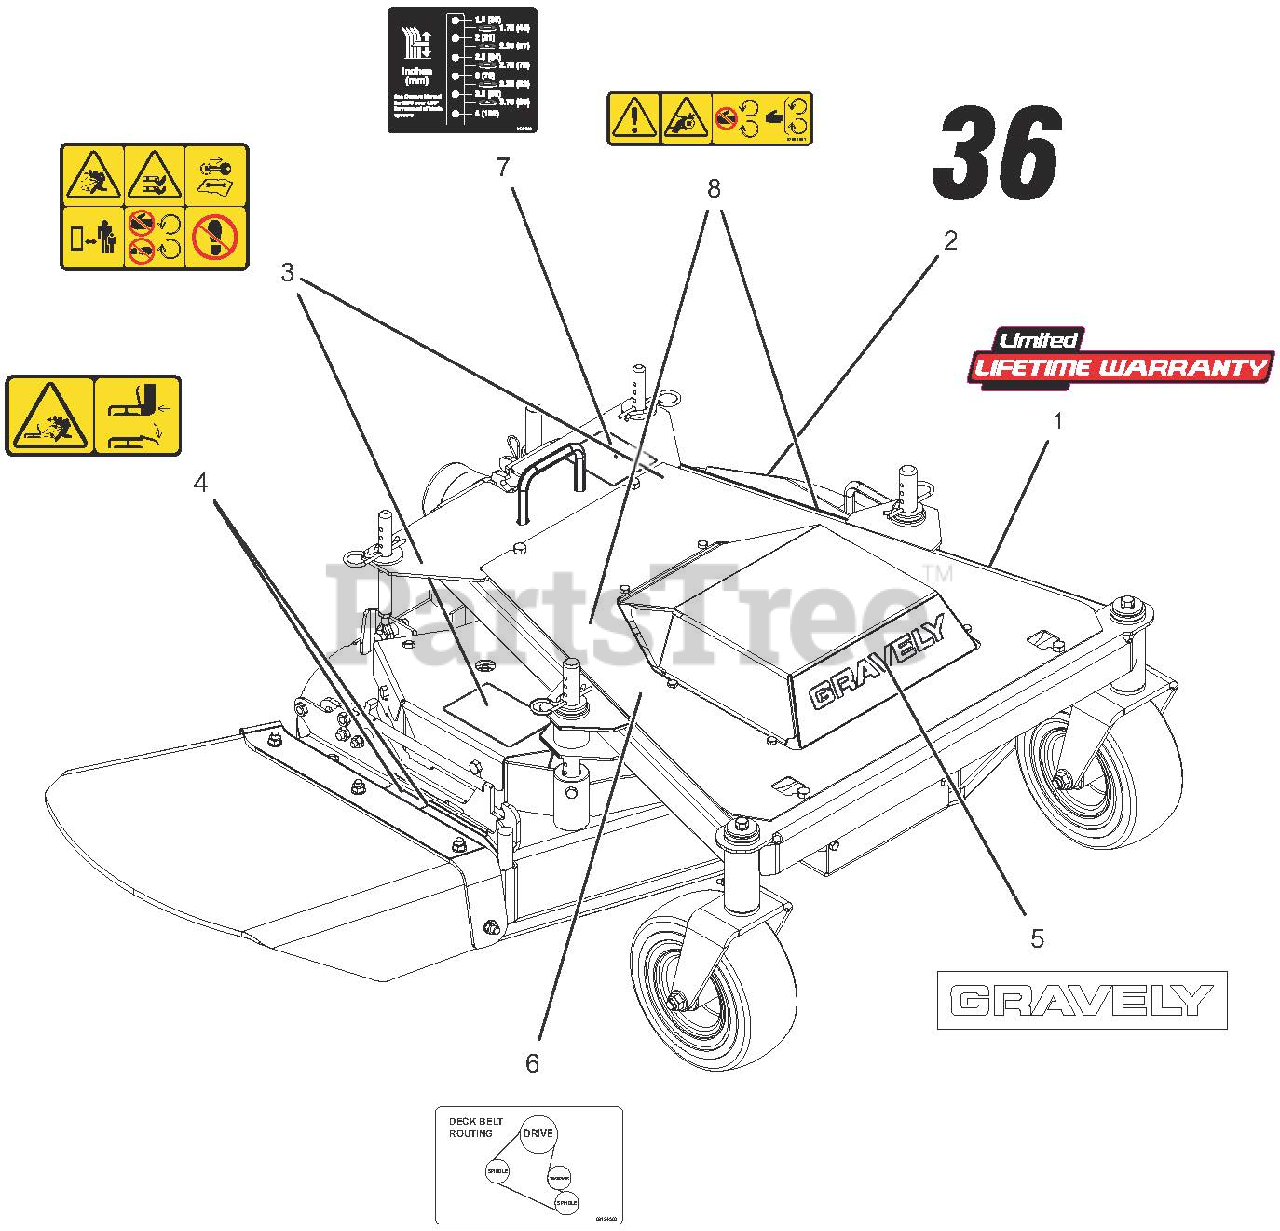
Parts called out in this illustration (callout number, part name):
1	DECAL, LIMITED LIFETIME WARR
2	DECAL, 36"
3	DECAL, SAFETY - MOWER DECK
4	DECAL, SAFETY - DECK GUARDING
5	DECAL, 9.5" GRAVELY LOGO
6	DECAL, BELT ROUTING 36" 2-WL
7	DECAL, PROWALK HEIGHT OF CUT
8	DECAL, SHIELD REMOVED
